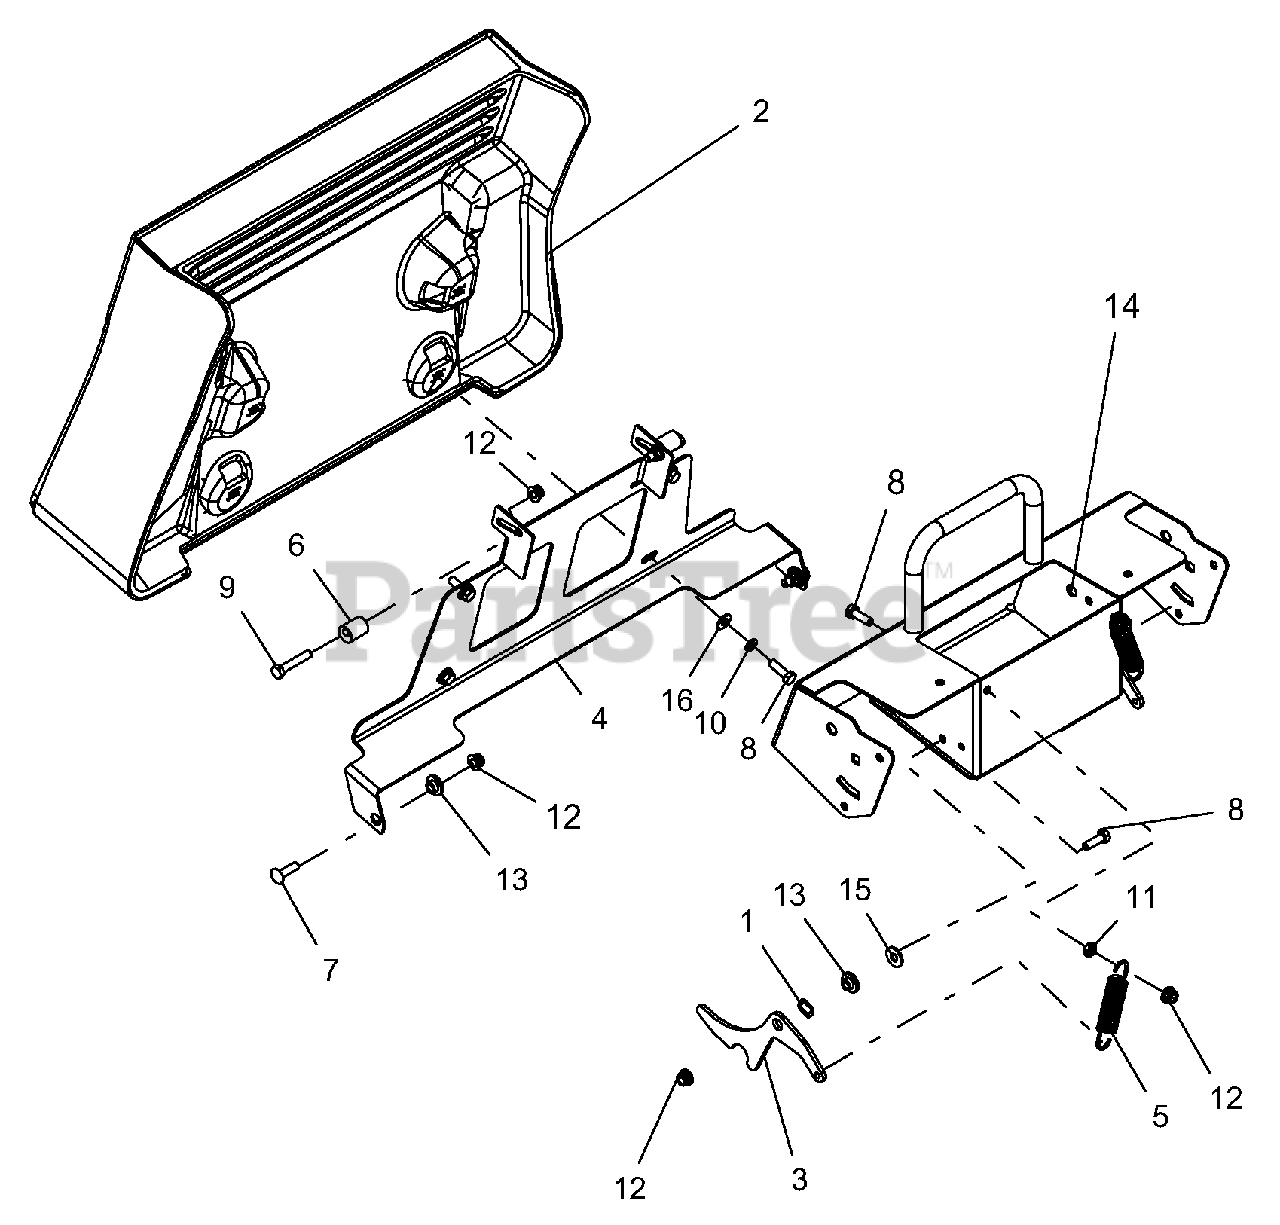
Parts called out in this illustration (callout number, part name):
1	WAVE WASHER .531X.781X.125 FH
2	PAD, PROSTANCE
3	LATCH, PAD MOUNT
4	PAD, MOUNT-RED
5	SPRG, EXTENSION
6	ECCENTRIC
7	BLT-RDHDSQSHNK .31-18X1.125 G5YWZC
8	BLT-HEX .31-18X1.00 GR5 YWZC
9	BLT-HEX .31-18X1.75 GR5 YWZC
10	WSHR-LK .31X.078 REG YWZC
11	@NUT-LK-CTR-JAM .31-18 YWZC
12	NUT-LK-NYL-FLG .31-18 YWZC
13	BSHG, FLG .32X.500.344X.880
14	WLDMT, CONTROL PANEL, PRO-STANCE
15	WSHR-FL-STL.38X.875X.083 YWZC
16	WSHR-FL-STL.312X.734X.065 YWZ
